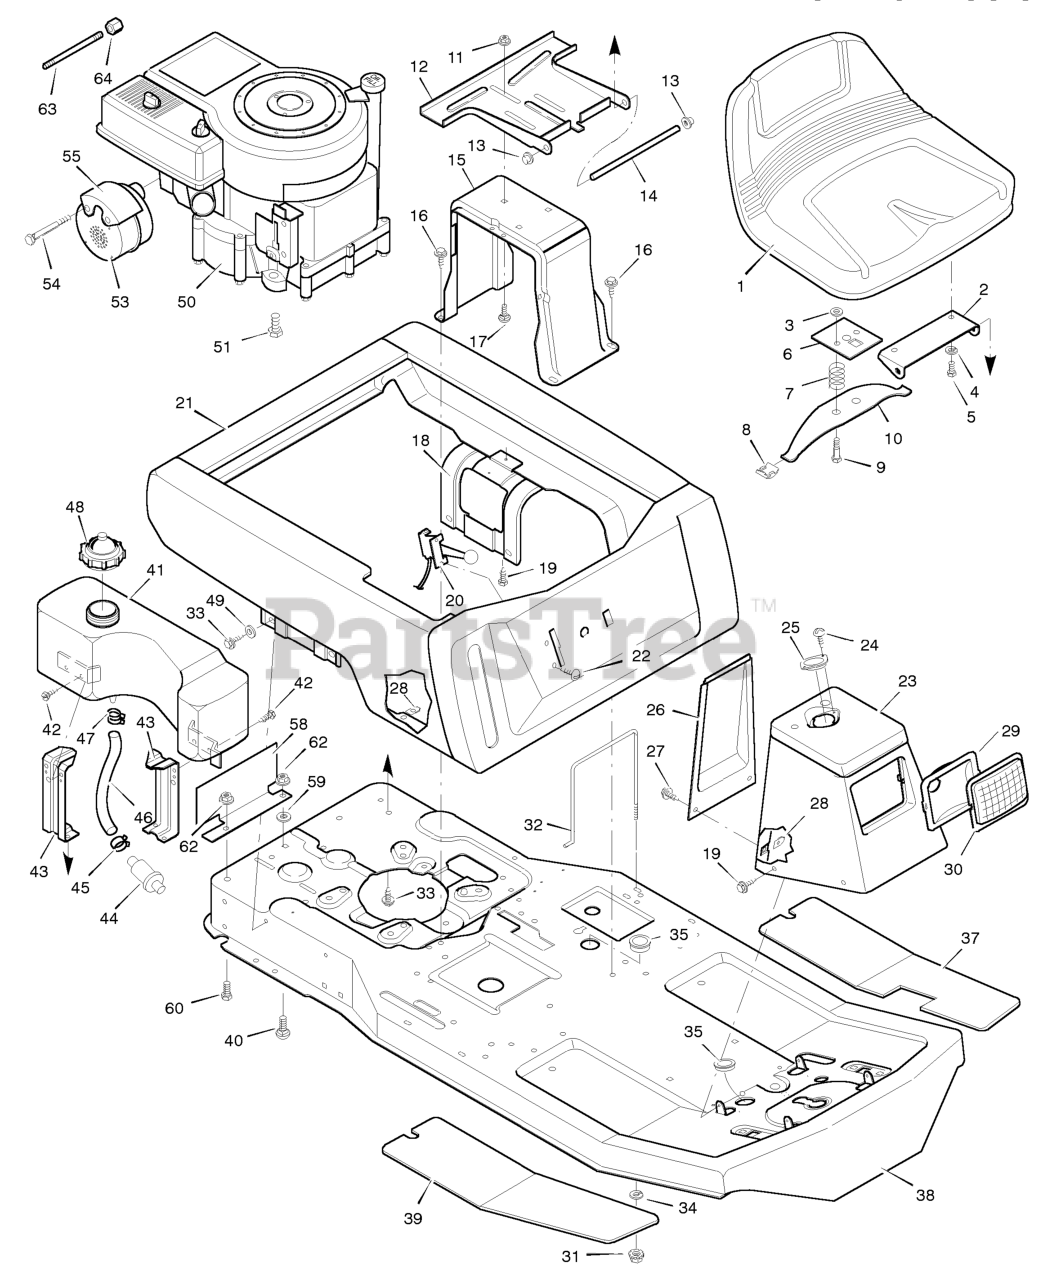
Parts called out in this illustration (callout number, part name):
2	Hinge, Seat
3	Retainer
4	Lockwasher
5	Bolt, Hex
6	Plate, Seat Switch
7	Spring, Compression
8	Glide, Seat Spring
9	Bolt, Shoulder
10	Spring, Seat
11	Locknut, Flange
12	Bracket, Seat Pivot
13	Cap, Push On
14	Rod, Seat Hinge
15	Support, Seat
17	Bolt, Carriage
18	Support, Body
20	Throttle Control
23	Console Assembly
25	Bearing, Steering Post
26	Console, Plate
28	J- Nut
29	Reflector
31	Locknut
32	Clamp, Battery
35	Grommet
37	Mat, Left
38	Frame Assembly
39	Mat, Right
40	Bolt, Carriage
41	Tank, Fuel
43	Bracket, Fuel Tank
44	Filter, Fuel
46	Line, Fuel
47	Clamp
48	Cap, Fuel
49	Washer
50	Engine *
51	Bolt, Engine Mount
53	Muffler
55	Shield, Heat
58	Shield, Heat
59	Washer
60	Bolt
62	Locknut, Flange
63	Pipe, Oil Drain
64	Cap, Oil Drain
